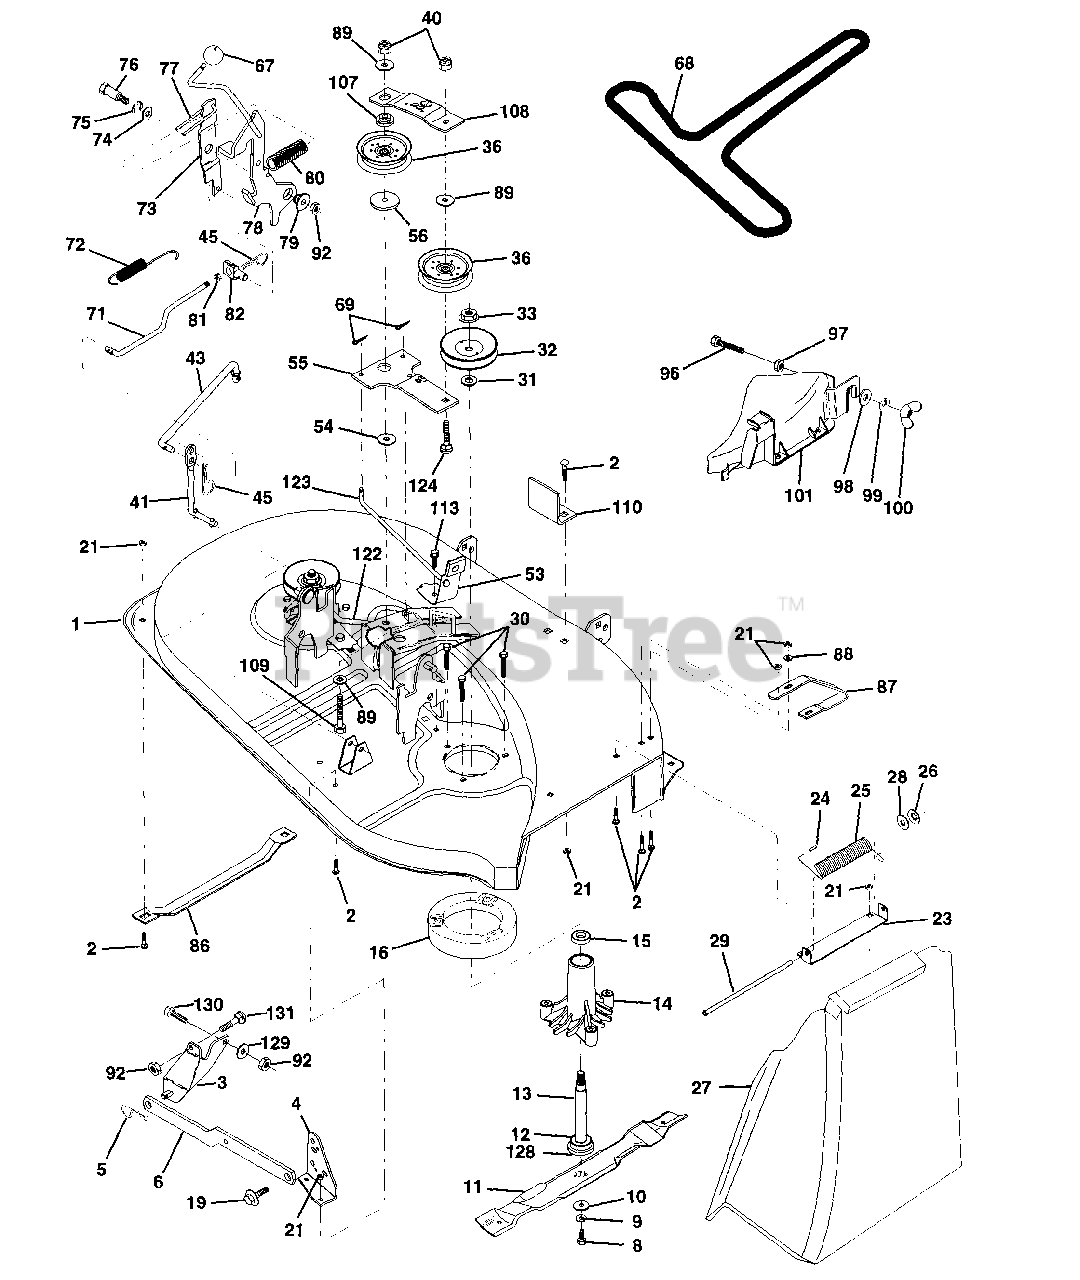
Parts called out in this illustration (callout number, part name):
1	Deck Asm Weldment
2	Bolt Rdhd Sqnk 5/16-18 unc X 3/4
3	Bracket Asm Fr Sway Bar 38/42
4	Bracket Asm Deck Sway Bar
5	Retainer Spring
6	Arm Suspension Rear
8	Bolt 3/8 - 24 X 1.25 Gr 8
9	Washer Lock Hvy 3/8
10	Washer Hard Blade Mower Vented
11	Blade Mower Mulching 38"
12	Bearing Ball #6024 (Mandrel)
13	Shaft Asm W/lower Bearing
14	Housing Mandrel Vented
15	Bearing Ball Mandrel
16	Stripper Mower Vented
19	Bolt Shoulder
21	Nut Crownlock 5/16-18 UNC
23	Bracket Deflector Mower
24	Cap Sleeve 80 x 112 Blk Mower
25	Spring Torsion Deflector 2 52
26	Nut Push Phos & Oil
27	Shield Deflector
28	Washer 11/32 X 5/8 X 16 Ga
30	Screw Thdrol Hex Head Zinc Mwr
31	Washer Spacer Mower Vented
32	Pulley Mandrel
33	Nut 9/16 Toplock Flng Oil Dip
36	Pulley Idler Flat 3 060
40	Nut Crownlock 3/8-16 UNC
41	Rod Pivot W/nibs
43	Rod Clutch Secondary
45	Spring Retainer 1" Zinc/cad
54	Washer Hardened
56	Spacer Retainer Pm Mower
67	Knob Rd 1/2-13 Plstc Thds Blk
68	V-Belt Mower
69	Pin, Cotter 3/32 x 3/4
71	Rod Clutch Primary 38/42
72	Spring Return
73	Arm Clutch Secondary
74	Washer 25/32 X 1-5/8 X 16 Ga
75	Ring Klip #t5304-75
76	Bolt Shoulder 3(8-16 Unc 1 44
77	Keeper Spring 4 000
78	Arm Asm Clutch Primary
79	Bushing 747 Od X 794 Lg Brass
80	Spring Clutch Mower
81	Nut Hex Jam 3/8-16
82	Trunnion Adj 94
86	Runner, LH
87	Runner, RH
88	Washer 11/32 x 3/4 x 16 Ga.
89	Washer 13/32 x 1 x 12 Ga.
92	Nut Lock Hex W/Ins 3/8-16 Unc
96	Bolt 3/8-16 x 1-1/4 Mulcher
97	Nut Crownlock 3/8-16 UNC
98	Washer 13/32 x 1-1/4 x 16 Ga.
99	Washer Lock Hvy Hlcl Spr 3/8
101	Cover Asm Mulching 38"
107	Spacer, Retainer
108	Stiffener, Idler Arm
109	Bolt, Hex Head 3/8-16 x 2-1/2
110	Upstop Deck Front 38"
113	Screw Thdrol 5/16-18 X 3/4
122	Rod, Brake, LH
123	Rod, Brake, RH
124	Bolt, Carriage 3/8-16 x 1-3/4
128	Washer Felt
129	Washer 13/32 x 13/16 x 12 Ga.
130	Bolt, Fin Hex 3/8-16 UNC x 1 Gr. 5
131	Bolt, Rdhd Sqnk 3/8-16 x 1
